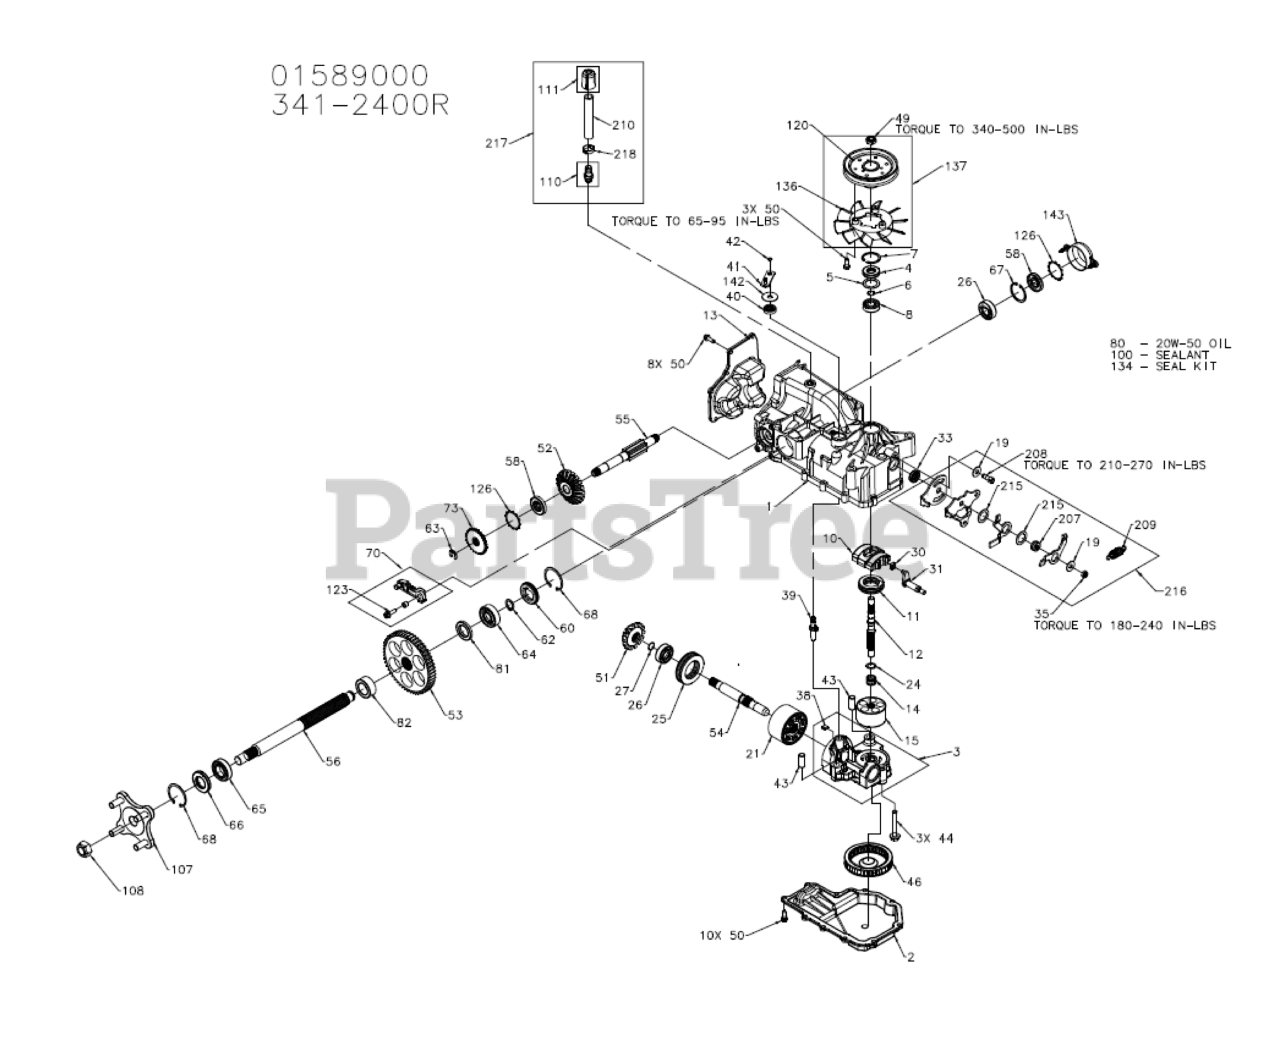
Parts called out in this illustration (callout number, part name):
1	KIT, MAIN HOUSING
2	HSG, IZT LOWER
3	KIT, C-SECTION
4	SEAL, LIP .5X.88X.25
5	WASHER .98X1.37X.04
6	RING, WIRE RETAINING
7	RING. RETAINING
8	BEARING, SHAFT BALL
10	SWASHPLATE. VARIABLE
11	BEARING. THRUST 30 X 52 X 13
12	SHAFT, INPUT
13	COVER, END IZT
14	SPRING. BLOCK
15	KIT, 10 CC BLOCK
21	ASSEMBLY BLOCK
24	WASHER. THRUST .59 X .79 X .04
25	BRG, THRUST BALL 42X68X16
26	BRG, BALL 17X40X12
27	RING, RET WIRE .561 ID
30	GUIDE. SLOT
31	ARM. TRUNNION TAPERED SQUARE
33	SEAL, LIP 12X25X7
35	NUT, LOCK, 5/16-24 UNF
38	KIT, BYPASS PLATE
39	ACTUATOR, BYPASS
40	SEAL, LIP
41	ARM. BYPASS
42	RING, RETAINING
43	PIN-HOLLOW .39X.5X1.
44	HFHCS 3/8-24X2.5 (PATCH)
49	HEX LOCK NUT, 1/2-20 (NYLON INSERT)
50	HFHCS 1/4-20X.75
51	GEAR, BEVEL 14T
52	GEAR, BEVEL 19T
53	GEAR, SPUR 53T
54	SHAFT, MOTOR
55	SHAFT, BRAKE
56	AXLE, 1.0X12.3
58	SEAL, LIP 17X40X7
60	PLUG, SEAL 1.86
62	RING, RET .75 EXT
63	RING, RET .440 EXT
64	BRG, BALL 20X47X14
65	BRG, BALL 25X47X12
66	SEAL, LIP 25X47X7
67	RING, RET 1.56 INT
68	RING, RET 1.87 INT
70	BRAKE ARM,RH IZT
73	BRAKE, PARK SPLINE
80	FLUID, HYDRO 20W50 QT
80	FLUID, HYDRO 15W50 QT
100	SEALANT TUBE 10.1OZ.
107	ASSEMBLY, HUB
110	FTG-STR .50 O-RING
111	BREATHER ASSEMBLY
120	PULLEY, 4.5 IN
123	SCREW, HFH 1/4-28 X 7/8 PATCH
126	RING, RET 1.43"
134	KIT, SEAL
136	FAN-6IN
137	KIT, FAN/PULLEY
142	WASHER, .392 X 1.250 X .0
143	CAP, BRAKE
208	SHCS 5/16-24X.75
209	SPRING, EXTENSION
210	HOSE .5X4
215	Assembly, RTN
216	KIT, CCW RTN SCISSOR
217	KIT, BREATHER
